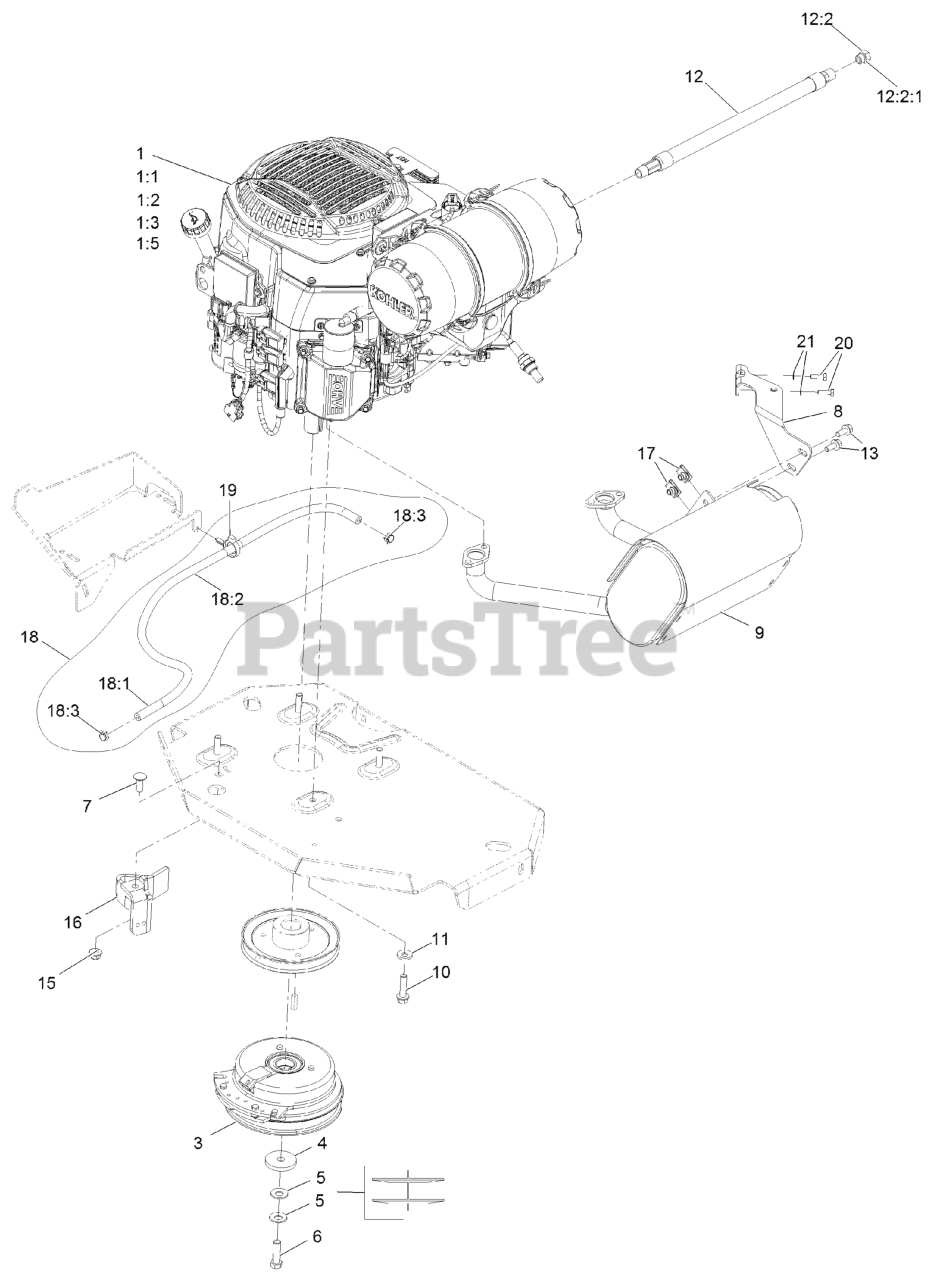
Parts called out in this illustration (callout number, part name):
1:1	Kohler 52 050 02-S Engine Oil Filter
1:2	Kohler 25 083 01-S Engine Air Filter
1:3	Kohler 25 083 04-S Safety Filter
1:5	Kohler 25 050 42-S Fuel Filter
3	CLUTCH KIT
4	WASHER-CLUTCH
5	WASHER-SPRING
6	SCREW-HH 7/16-20 X 1 1/2 W/LOCTITE
7	SCREW-CARR
8	MUFFLER BRACKET KIT
9	MUFFLER KIT
10	SCREW-HWH
11	WASHER-BELLEVILLE
12	OIL DRAIN HOSE ASM
12:2	PLUG-HH
12:2:1	O-RING
13	SCREW-HHF
15	NUT-HF, NI
16	CLUTCH-ANCHOR
18	FUEL LINE ASM
18:1	HOSE-FUEL
18:2	SLEEVE-THERMAL
18:3	CLAMP-HOSE
19	CLAMP-HOSE
20	SCREW-HH M6-1 X 20Mm W/Patch
21	WASHER-SPRING
